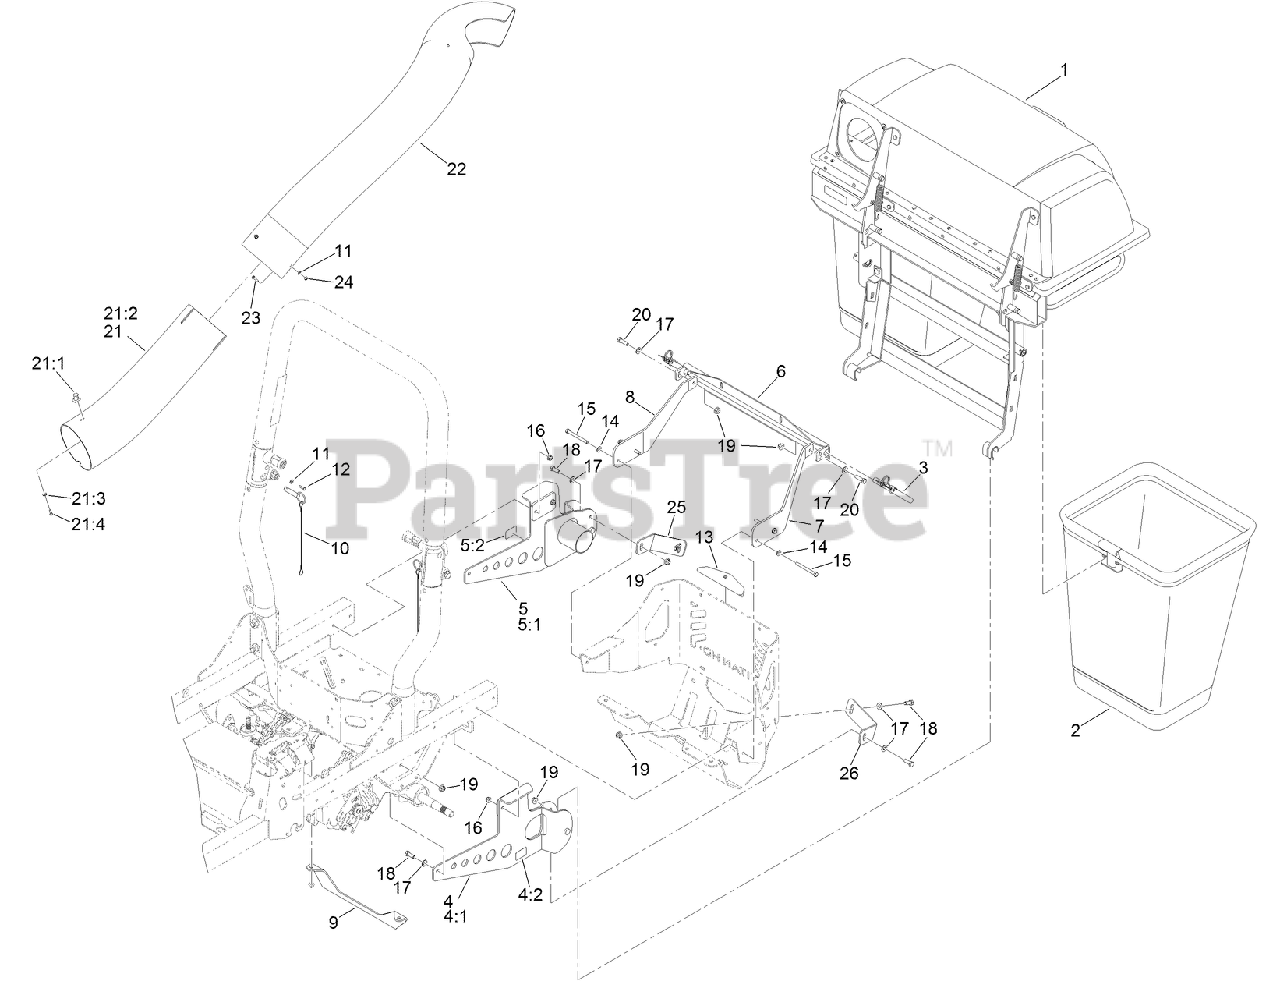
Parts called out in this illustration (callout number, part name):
1	TWIN BAG HOOD ASM
2	BAG AND FRAME ASM
3	PIN-MOUNT, BAGGER
4	SUPPORT-BAGGER, LOWER LH
4:1	SUPPORT-BAGGER, LOWER LH
4:2	DECAL-WARNING
5	SUPPORT-BAGGER, LOWER RH
5:1	SUPPORT-BAGGER, LOWER RH
5:2	DECAL-WARNING
6	SUPPORT-BAGGER, UPPER
7	BRACKET-UPPER, LH
8	BRACKET-UPPER, RH
9	SUPPORT-TRANSMISSION
10	HITCH PIN ASM
11	WASHER-FLAT
12	SCREW
13	COVER-HITCH
14	WASHER-PLAIN
15	SCREW-HH
16	NUT-HF, NI
17	WASHER-FLAT
18	SCREW-HH
19	NUT-HF, NI
20	SCREW-HH
21	LOWER TUBE ASM
21:1	TUBE-LOWER, SHORT
21:2	LATCH-KEEPER
21:3	SCREW-PPH
21:4	WASHER-FLAT
22	TUBE-UPPER
23	SCREW-HWH
24	NUT-LOCK, NI
25	BRACKET-BAGGER, RH
26	BRACKET-BAGGER, LH
